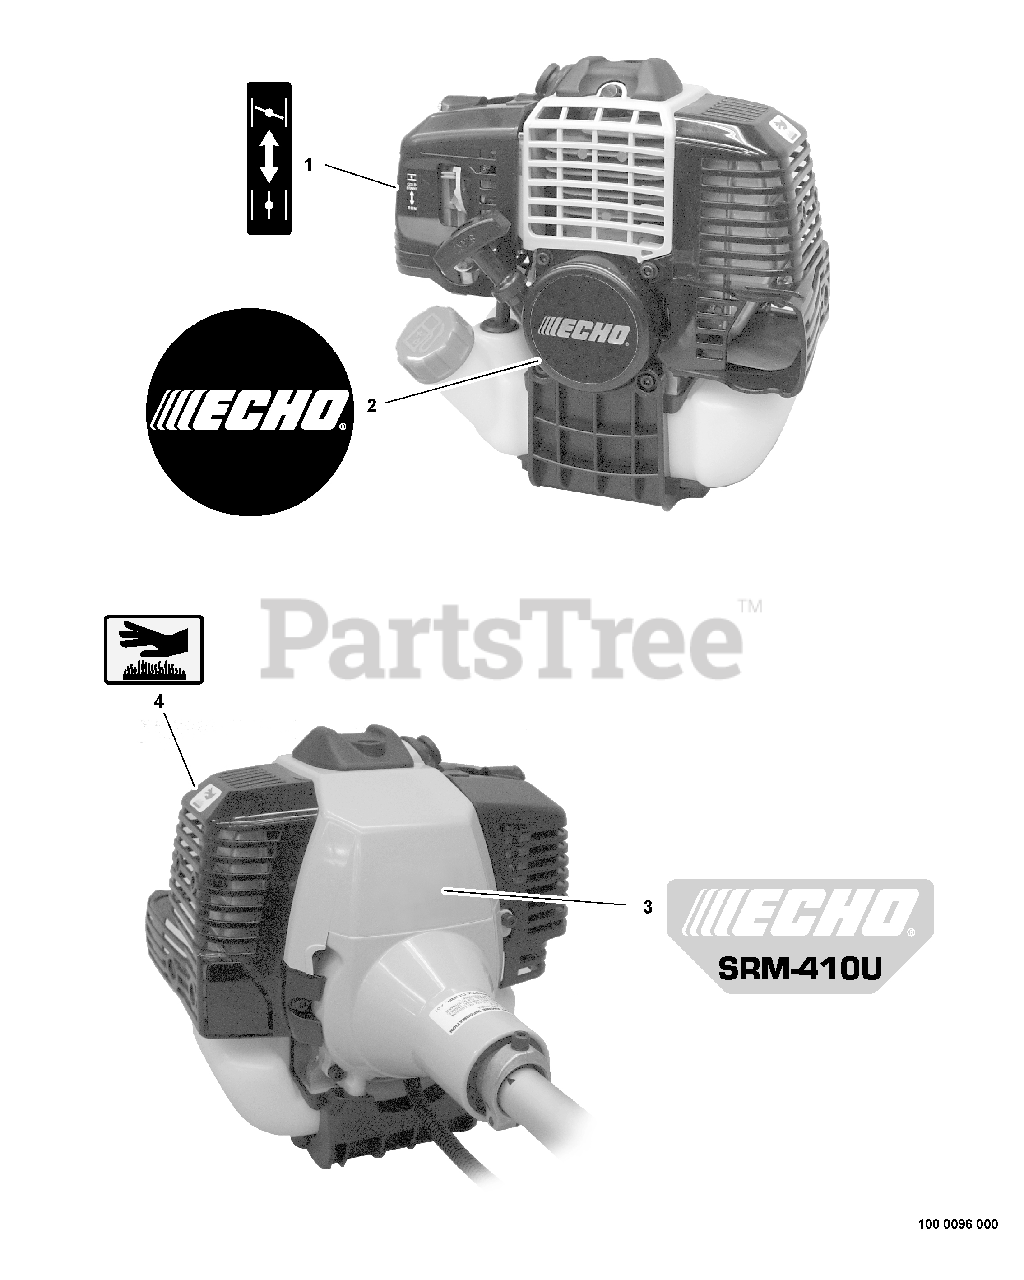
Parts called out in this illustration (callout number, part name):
1	LABEL - CHOKE
2	LABEL - ECHO
3	LABEL - MODEL SRM-410U
4	LABEL - HOT SURFACE
